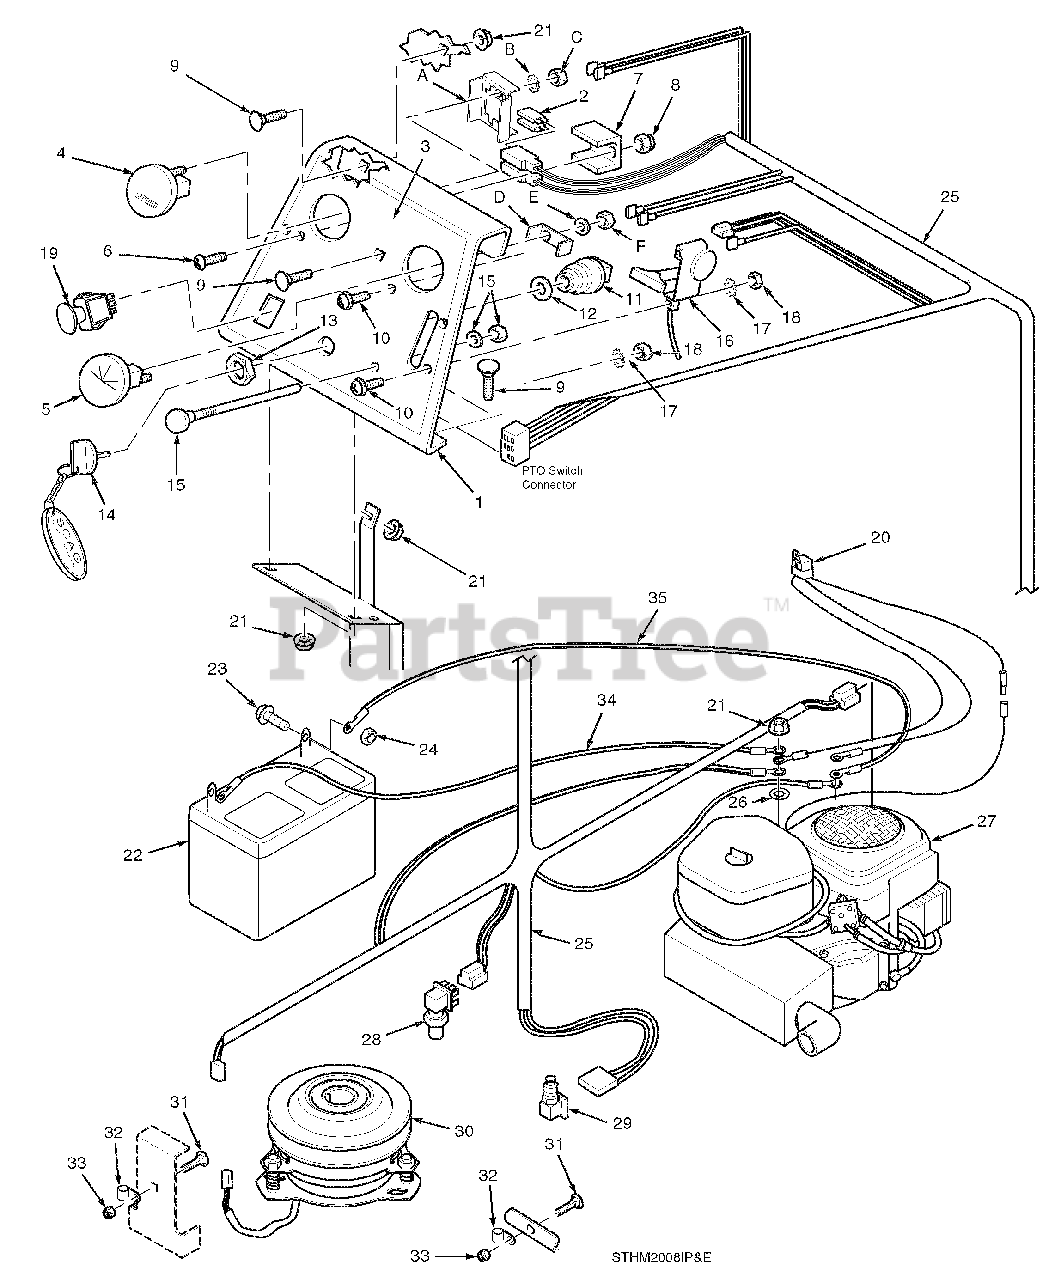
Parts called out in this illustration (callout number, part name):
1	Instrument Panel
2	Blade Fuse, 20 amp.
3	Decal, Instrument Panel
4	Hour Meter
5	Ammeter
6	Phillips Rd. Head Screw, #10-32 x 1-1/2"
7	Bracket, Fuse Holder
8	Elastic Stop Nut, #10-32
9	Carriage Bolt, 5/16-18 x 3/4"
10	Phillips Washer Head Screw, #10-32 x .50"
11	Keyswitch
12	Lockwasher, 5/8 Int. Tooth
14	Key Chain with Keys
15	Choke Control
16	Throttle Control
17	Lockwasher, #10 Ext. Tooth
18	Hex Nut, #10-32
19	Switch, PTO
20	Wire Harness With Relay
21	Serr. Fl. HH Nut, 5/16-18
22	Battery, 300 CCA
23	Bolt, Hex head 1/4-20 x 1/2"
24	Hex Nut 1/4-20
25	Wire Harness, STHM
26	Lockwasher 5/16 Int. Tooth
27	Engine, 23 HP Kohler CV
28	Switch, Parking Brake
29	Switch, Foot Safety
30	Clutch, Electric
31	Carriage Bolt, 5/16-18 x 3/4"
32	Wireloom
33	Locknut, Elastic Stop 5/16-18
34	Battery Cable, 36" Black
35	Battery Cable, 25" Red
A	Hour Meter Bracket
B	Lockwasher, #10 Ext. Tooth
D	Ammeter Bracket
E	Lockwasher, #10 Int. Tooth
